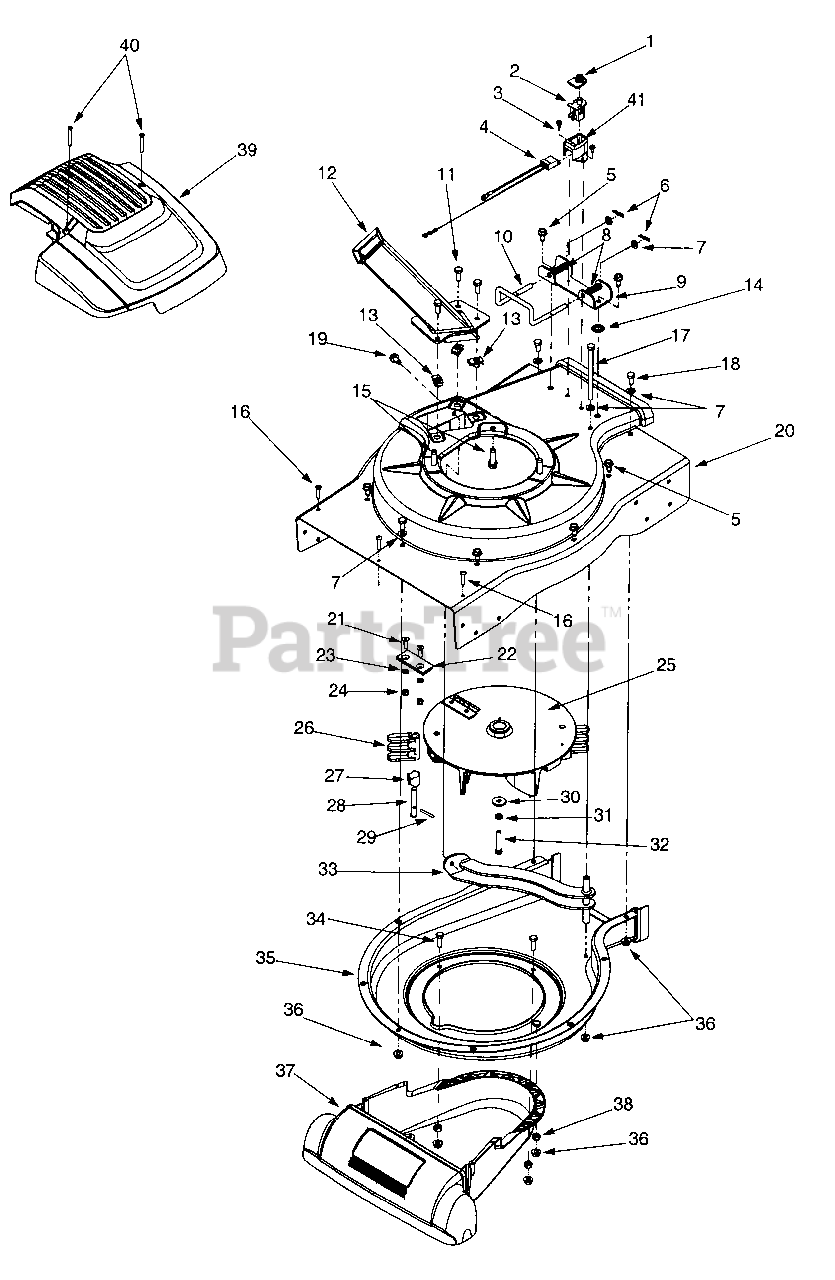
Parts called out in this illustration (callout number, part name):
1	Switch Cover
2	Safety Switch
3	Hex Washer Screw #10-16 x .50
4	Wire Harness
5	Hex Washer Screw 5/16-18 x .625
6	Cotter Pin
7	Flat Washer .330 ID x .630 OD
8	Compression Spring
10	Lock Rod
11	Hex Cap Screw 5/16-18 x .75
13	U-Clip Lock Nut 5/16-18
14	External Lock Washer 5/16
15	Hex Washer Screw 3/8-16 x 1.25
16	Screw #12-16 x 1.0
17	Hex Cap Screw 5/16-18 x 4.5
18	Hex Cap Screw 5/16-18 x .625
19	Hex Washer Screw 5/16-18 x .625
22	Chipper Blade
23	Lock Washer 5/16
24	Hex Lock Nut 5/16-24
25	Impeller Assembly
26	Flail Blade
27	Pin Clip
28	Clevis Pin
29	Spiral Pin
30	Flat Washer .375 ID x 1.25 OD
31	Lock Washer 3/8
32	Hex Cap Screw 3/8-24 x 2.0
34	Hex Cap Screw 5/16-18 x .875
36	Lock Nut 5/16-18
37	Nozzle Cover
38	Lock Nut 5/16-18
39	Shroud
40	Screw #8-18 x 1.25
41	Safety Switch Cover
